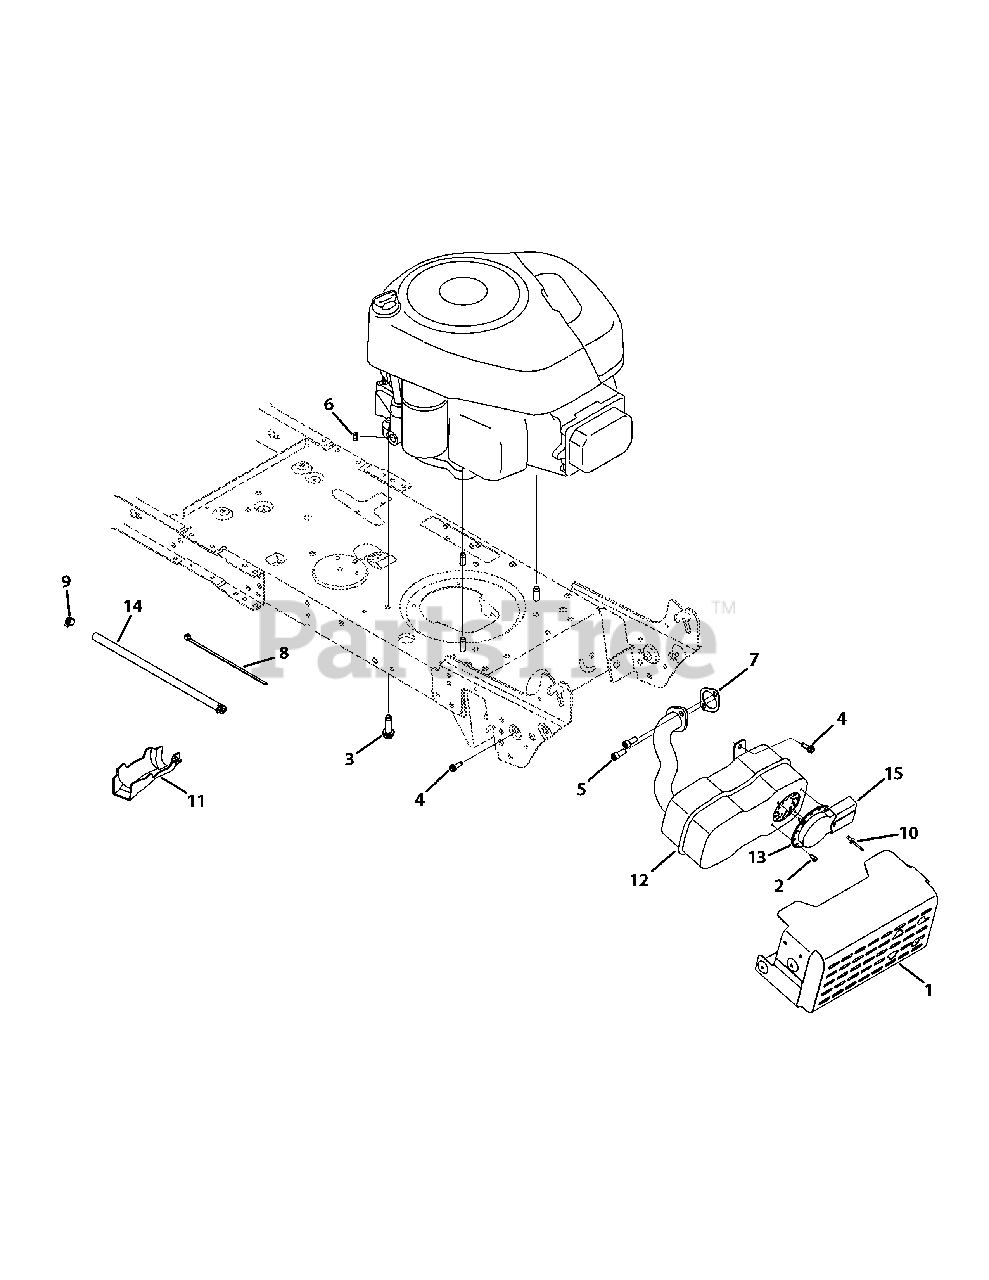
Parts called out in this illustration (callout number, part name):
2	Hex Wash HD AB S-Tapp Screw #8-.50
3	Hex Wash S-Tapp Screw 3/8-16 x 1.0
4	Thd Form ing Screw. 1/4-20 x .75 Lg.
5	Socket HD Cap Screw. 5/16-18 x .75
6	Sems Nut 1/4-20
7	Exhaust Gasket (B&S)
8	Cable Tie
9	Hose Clamp
10	Rivot, Pop, .188 x .3
11	Oil Drain Sleeve
12	Muffler, Single I let
13	Muffler Deflector
14	Fuel Hose, Low Permeation
15	Muffler Deflector
